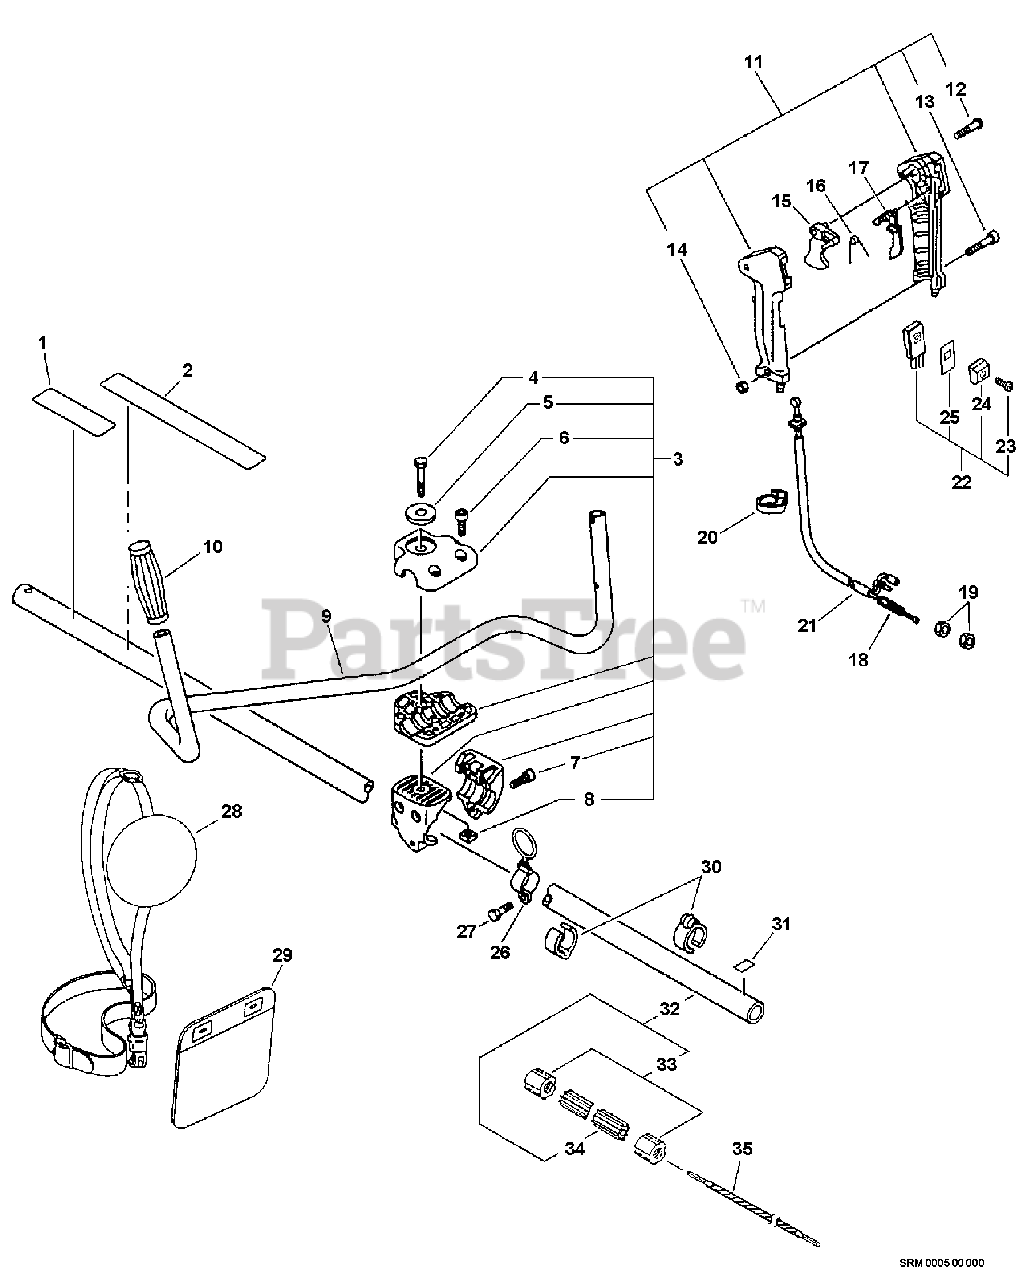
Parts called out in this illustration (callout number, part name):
1	LABEL, CAUTION
2	LABEL, CAUTION
3	BRACKET KIT, HANDLEBAR
4	BOLT 8×55
5	WASHER 8
6	BOLT 5×20
7	BOLT 5×30
8	NUT 8×1.25
9	HANDLEBAR
10	GRIP, HANDLE
11	CONTROL HANDLE KIT
12	SCREW 3×25
13	SCREW 5×30
14	NUT M5
15	TRIGGER, THROTTLE
16	SPRING, TORSION
17	LOCKOUT, THROTTLE
18	CABLE, THROTTLE
21	TUBE, FLEXIBLE 7×790
22	SWITCH, ON-OFF
23	SCREW 3×10
24	KNOB, SWITCH - ORANGE
25	LABEL, SWITCH
26	HANGER SET, HARNESS
27	BOLT 5×12
28	SHOULDER STRAP ASSY
29	PAD, HIP
30	CLIP, CABLE 25 MM
31	LABEL - ALIGNMENT
32	MAIN PIPE ASSY 25×1500
34	LINER, FLEXIBLE 21.6×1420
35	DRIVESHAFT - FLEXIBLE L= 1522
36	TOOL, LOCKING 5×120 MM
37	T-WRENCH 17x-19 L200
